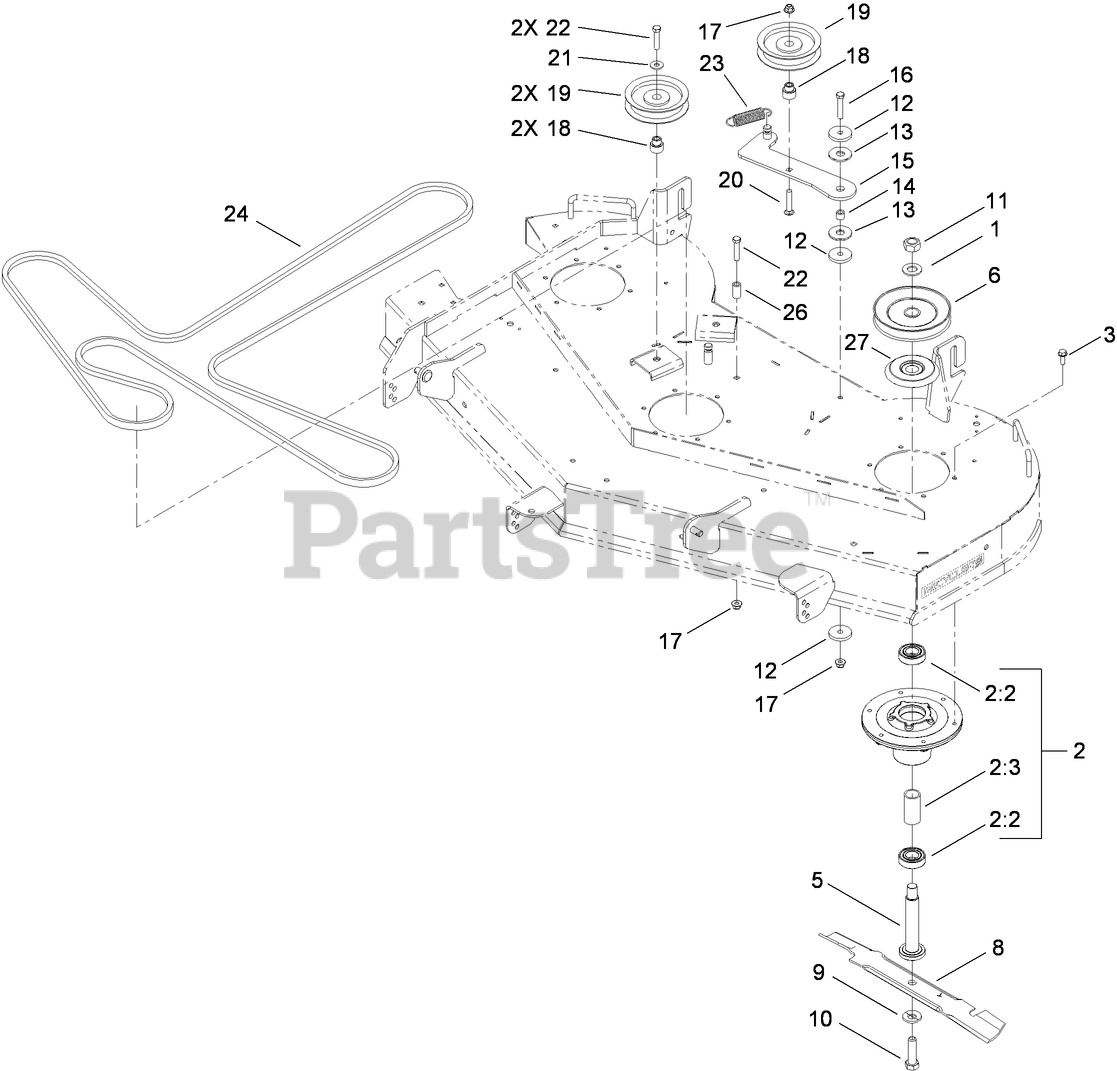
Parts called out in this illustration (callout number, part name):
1	WASHER
2:3	SPACER-BEARING
3	SCREW-TAPTITE
5	SHAFT-SPINDLE
6	PULLEY
8	BLADE-HI FLO
10	SCREW-BLADE
11	NUT-HEX
12	WASHER-PLAIN
13	WASHER-FRICTION, COMPOSITE
14	BUSHING-LEVER, LIFT
15	ARM-IDLER
16	SCREW-HH
17	NUT-HF, NI
18	BUSHING-IDLER
20	SCREW-CARR
21	WASHER-HARDENED
22	SCREW-HH
23	SPRING-EXTENSION
26	SPACER
27	SHIELD-BEARING
